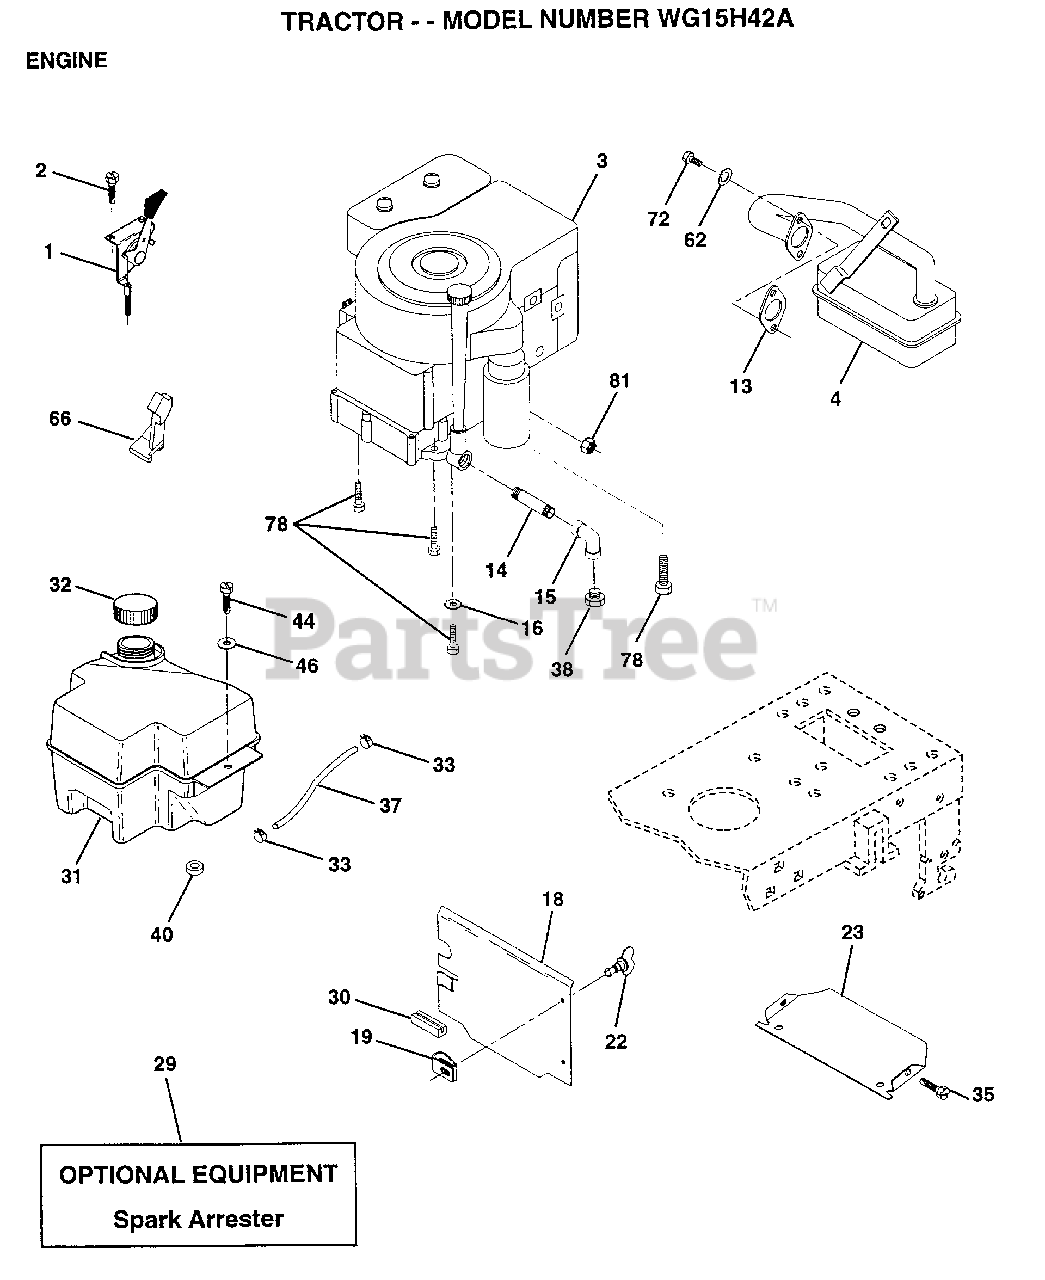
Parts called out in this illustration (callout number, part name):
1	CONTROL.THTL.23.5
2	SCREW LT
3	ENG. B&S 15.0 MODEL
4	MUFFLER
13	GASKET ENG 1 313 LD TIN PLATED
14	PIPE NIPPLE
15	ELBOW
16	LOCKWASHER
18	SHIELD HEAT
19	RECEPTACLE LT
22	"STUD 1/4 TURN,BUS"
32	CAP ASM FUEL
33	HOSE CLAMP
35	SCREW
37	LINE FUEL
44	SCREW HEX CRT
46	WASHER
62	LOCKWASHER
66	"STOP,DASH THROTT"
72	SCREW
78	SCREW
81	NUT
